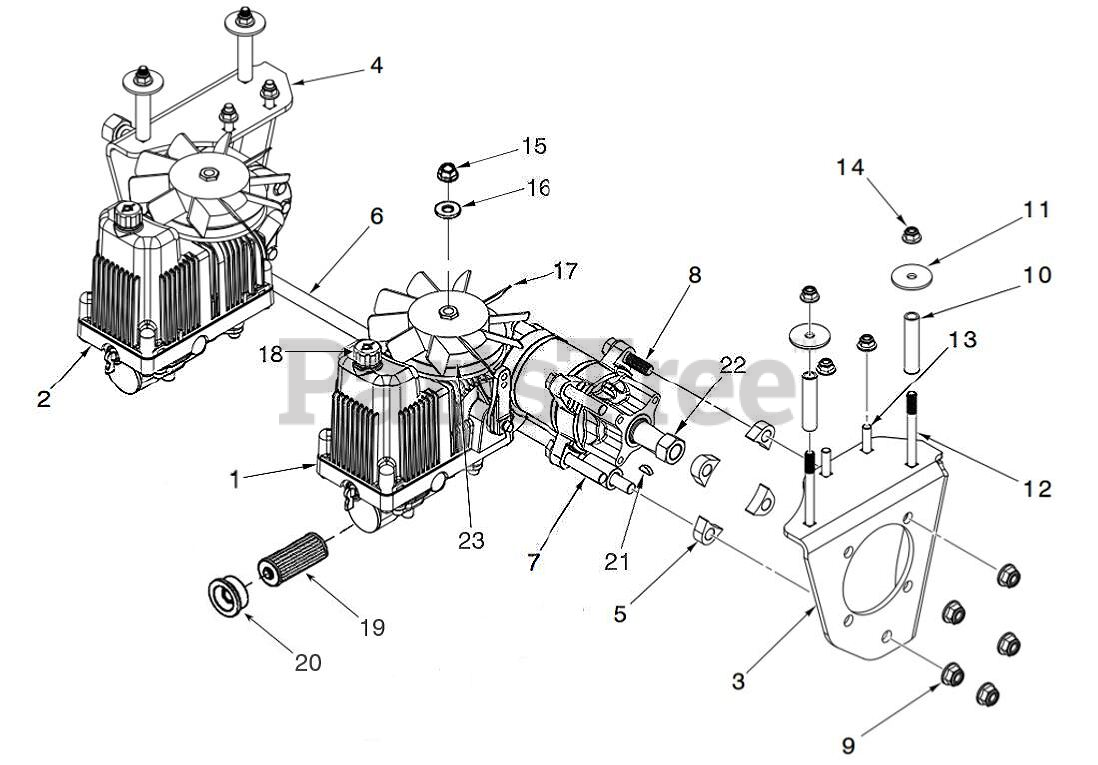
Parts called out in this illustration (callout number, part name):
1	Transmissions
2	Transmissions
3	Brackets
4	Brackets
6	Cross
9	NUT 1/2-13 HEX FLANGE NYLOK CL
10	Tubes
12	RHSNB 3/8-16 X 4 GR5 ZD
13	GSPW Bolts
14	GSPW Nuts
19	Filters
22	Axles
